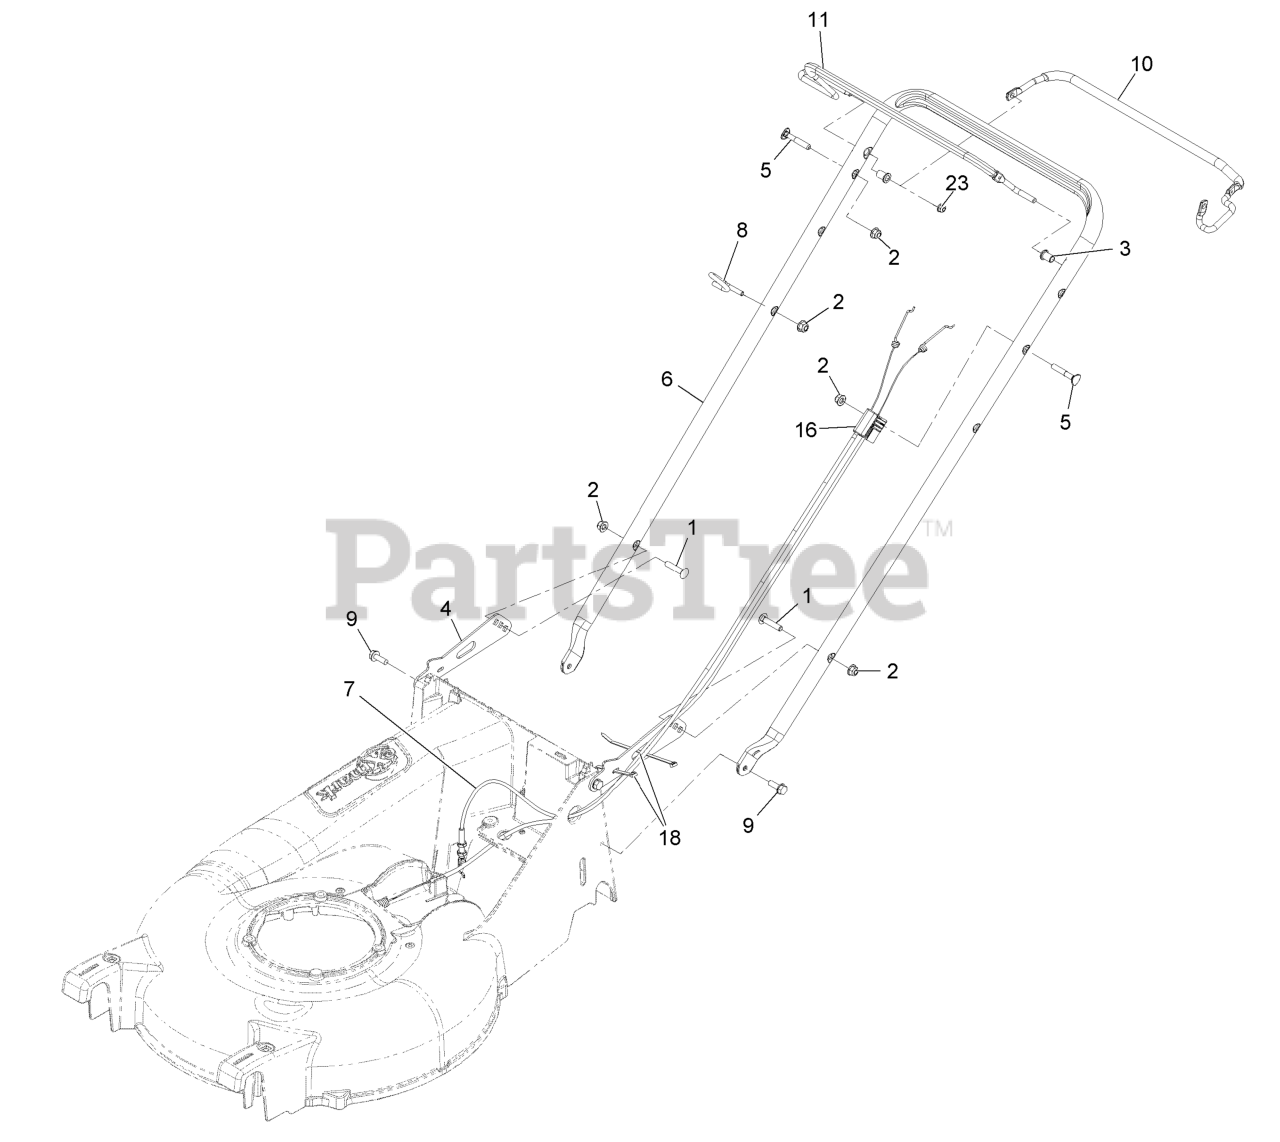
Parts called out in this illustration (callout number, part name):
1	Bolt-Carriage 5/16-18 X 1 1/2
2	Nut-Nyloc 5/16-18 Flg
3	Bushing-Handlebar
4	Bracket,Handlebar
5	Bolt-Carriage 5/16-18 X 2
6	Handlebar-P21
7	Cable, Drive Ec21
8	Guide,Rope
9	Screw-HWH 3/8-16 X 7/8 Taptite
10	Bail-Drive
11	Bail,OPC/BBC
16	Cable-Zone Kawasaki
18	Tie-Cable
23	Nut-Nyloc 1/4-20 Flg
